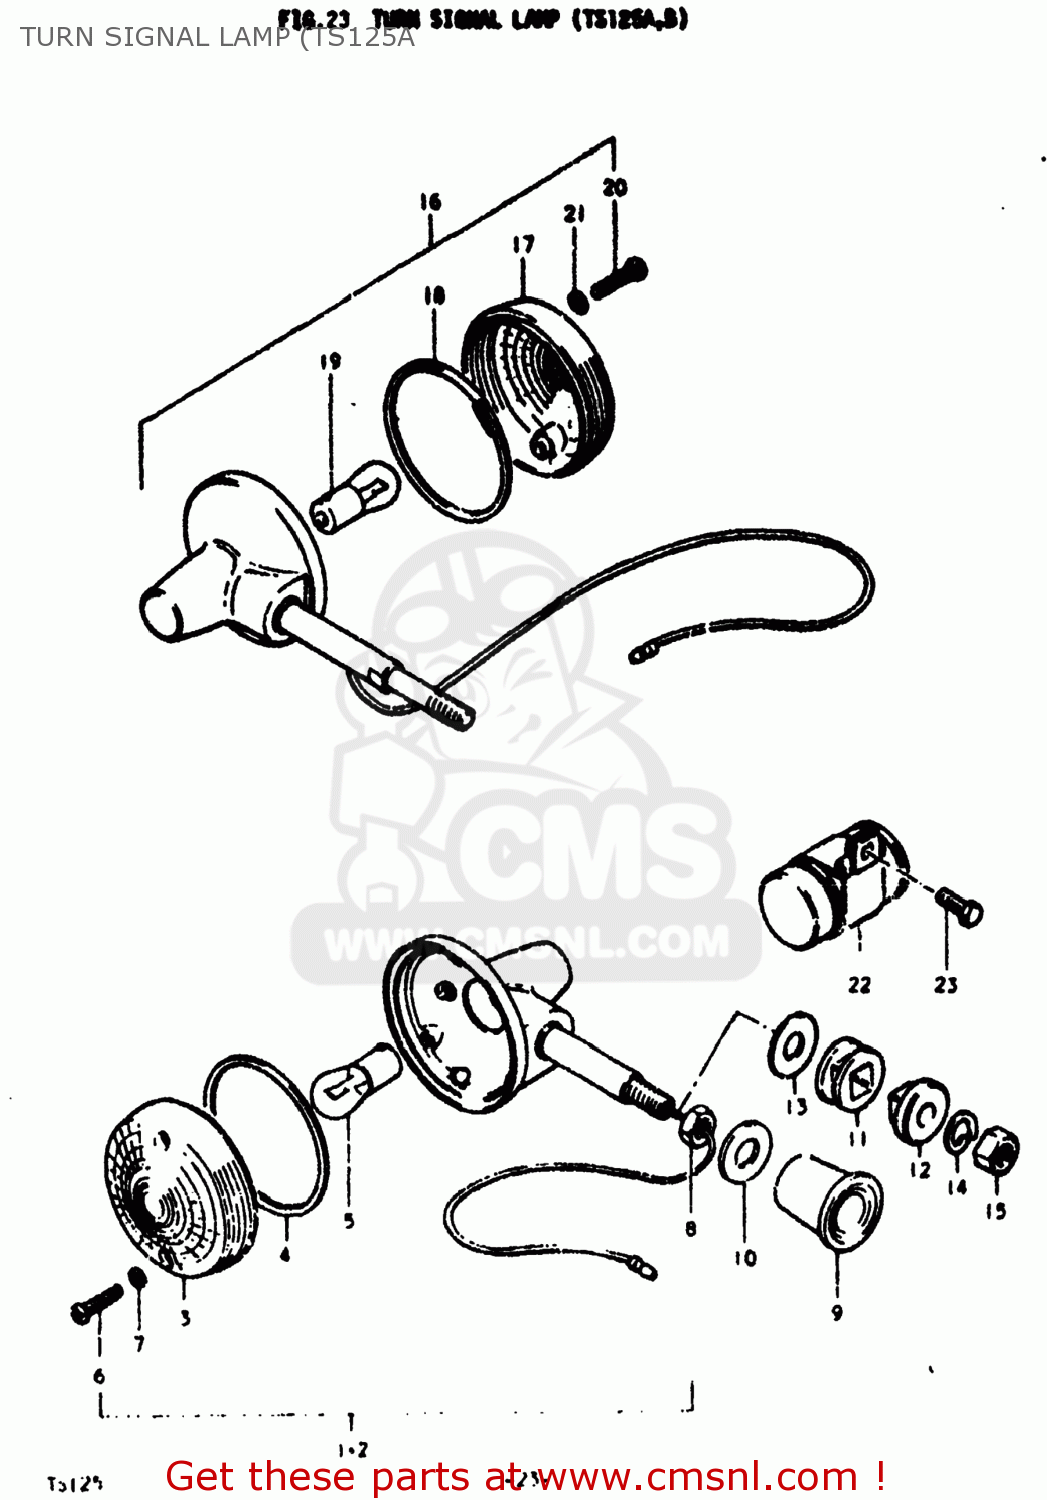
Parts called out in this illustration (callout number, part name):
1	LAMP ASSEMBLY,FRONT TURN SIGNAL
2	LAMP ASSEMBLY,FRONT TURN SIGNAL
3	LENS
4	GASKET (NAS)
5	BULB(6V17W,STANLEY,A4513A)
6	SCREW
7	GASKET (NAS)
8	NUT
9	COVER,FRONT TURN SIGNAL BRACKET
10	WASHER
11	CUSHION
12	SPACER,RR TURNSIGNAL LAMP
13	WASHER (10.5X30X2.3)
14	LOCK WASHER
15	NUT
16	LAMP ASSEMBLY,REAR TURN SIGNAL
17	LENS
18	GASKET (NAS)
19	BULB(6V17W,STANLEY,A4513A)
20	SCREW
21	GASKET (NAS)
22	RELAY,TURN SIGNAL
23	BOLT
